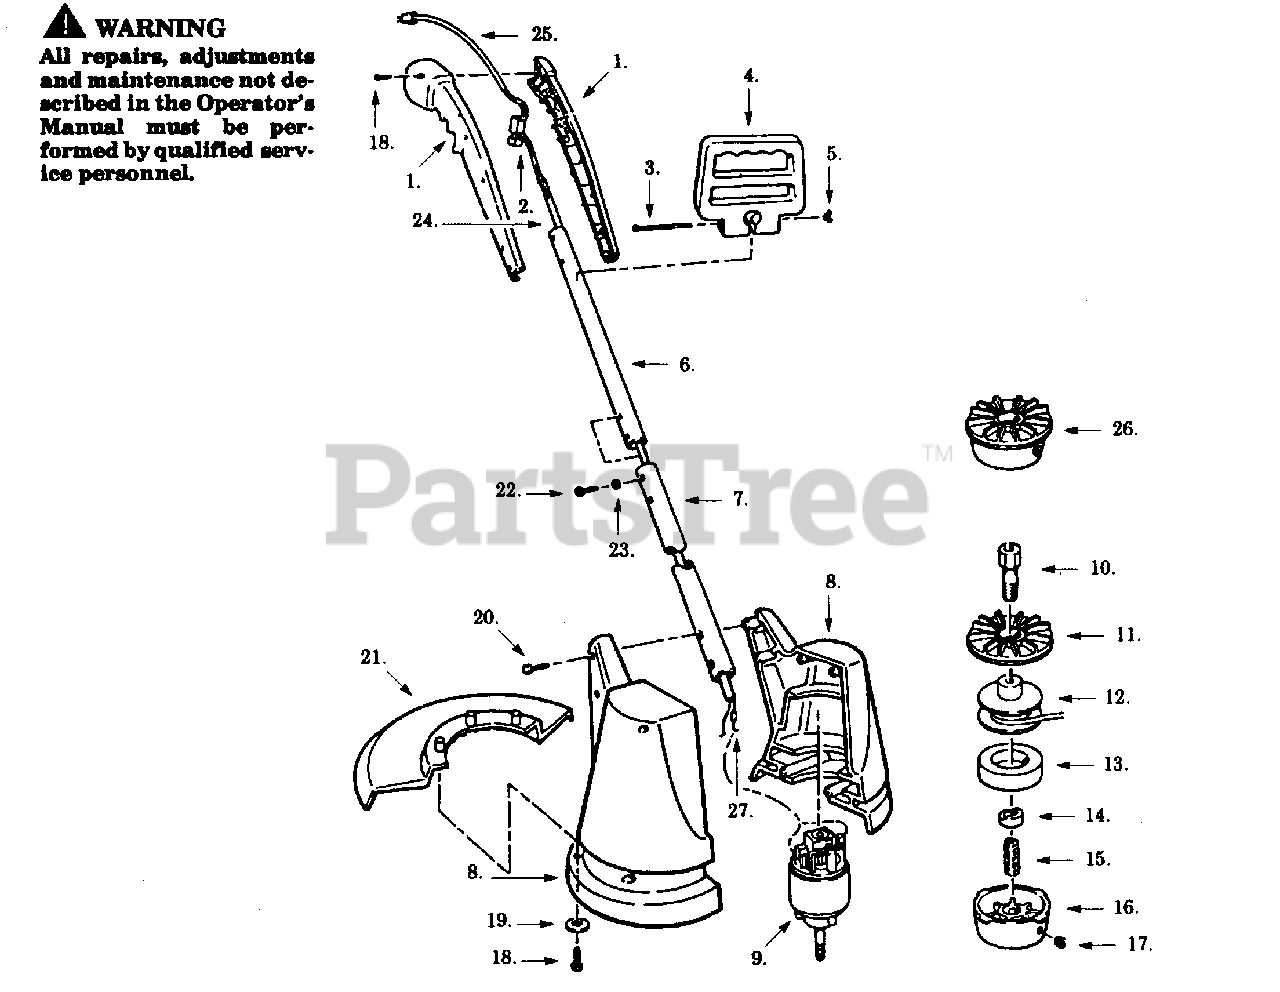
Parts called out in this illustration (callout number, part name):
1	R.H./L.H. Handle
2	Trigger Switch
4	Side Handle
5	Wing Nut
6	Upper Handle Tube
7	Lower Handle Tube
8	R.H./L.H. Housing
10	Drive Adapter
11	Rear Plate
12	Spool & Line
13	Foam Pad
14	Drive Adapter Nut
21	Line Cutter Guard
23	Lockwasher
25	Power Cord
26	Cutting Head Ass'y.
27	Rectifier
